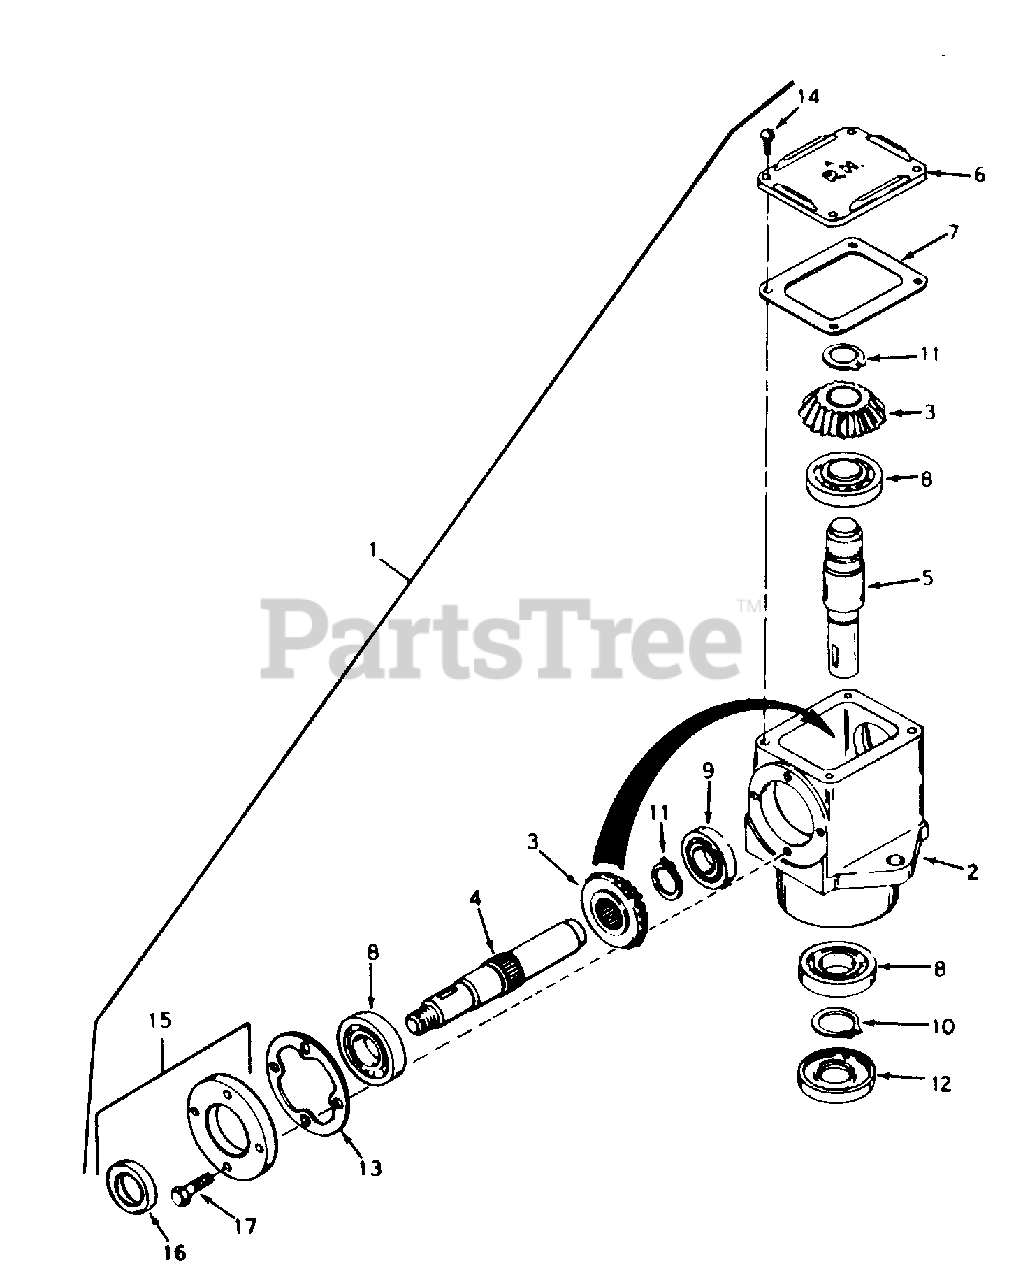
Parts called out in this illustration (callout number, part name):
1	Head Ass'y. R.H.
2	Housing, Right Angle Drive
3	Gear, Miter
4	Shaft, Input
5	Shaft, Output
6	Cover, Right Hand
7	Gasket, Cover
8	Bearing, Ball
9	Bearing, Ball
10	Ring, Snap
11	Ring, Snap
12	Seal, Oil
13	Gasket, Cap
14	Screw, Rd. Hd. Self-Tap. 10-24 x 1/2
15	Cap & Seal Ass'y., Retainer
16	Seal, Oil
17	Screw, Hex Hd. 1/4-20 x 7/8
